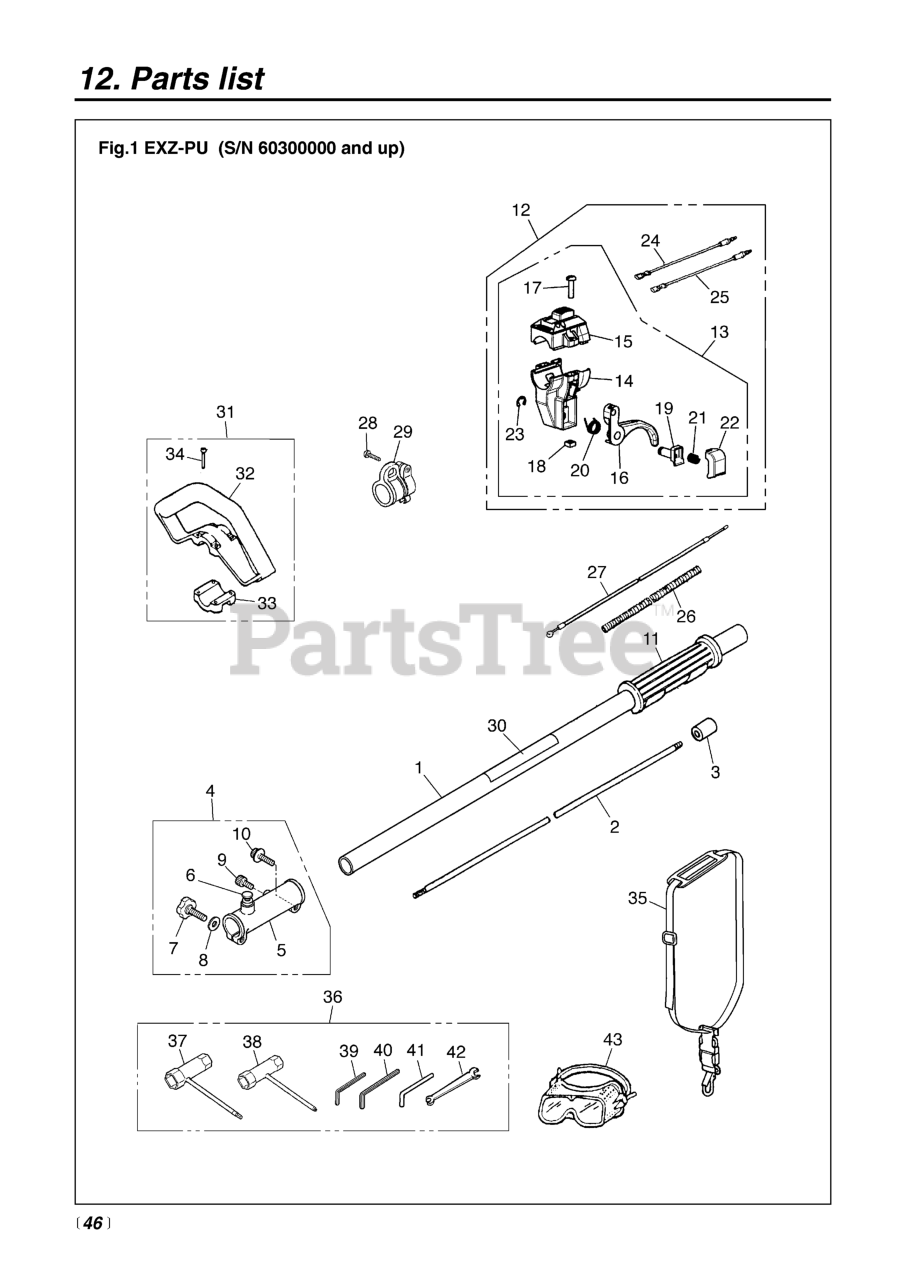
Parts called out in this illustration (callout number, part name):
1	PIPE COMP
2	SHAFT
3	SPACER
4	JOINT, PIPE ASSY
5	JOINT
6	STOPPER COMPLETE
7	BOLT, KNOB
8	WASHER, M8 x 2.3 (RPLS -20823)
9	BOLT, M5 X 10
10	BOLT, M6 x 1.35
11	GRIP
12	LEVER ASSY
13	LEVER
15	COVER COMP. (RP. 6110-14410-02)
16	FLEX, TRIGGER
24	CORD (A), BLACK
25	CORD (B), RED
26	TUBE (RPLS 4900-72141)
27	CABLE (RPLS 5580-83100)
28	HANGER COMP.
29	SCREW, M5X20 (RPLS.1400-75510)
30	PLATE, NAME
31	HANDLE ASSEMBLY
32	HANDLE
34	SCREW, M5 x 35
35	STRAP ASSY.
36	TOOL SET
37	SOCKET
38	SOCKET
39	WRENCH (TOOL)
40	WRENCH (TOOL)
41	BAR
42	SPANNER, 8 X 10 (RPLS 2540- )
43	GOGGLE
